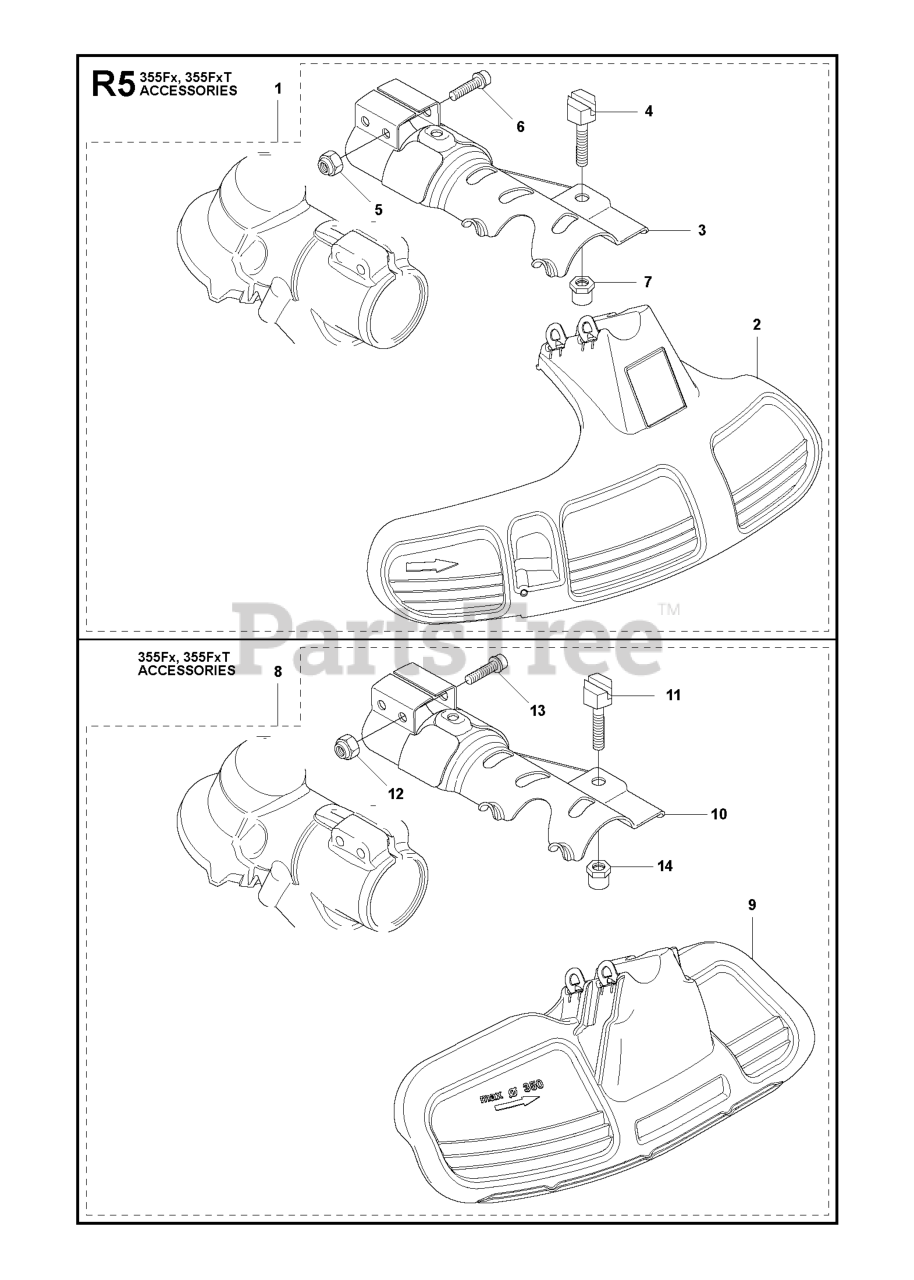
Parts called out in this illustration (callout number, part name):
1	GUARD ASSY
2	PROTECTION
3	ATTACHMENT PLATE
5	LOCKNUT M6
7	SPACING SLEEVE
8	GRASS BLADE GUARD ADAPTER INCL
9	BLADE GUARD GRASS
10	ATTACHMENT PLATE
12	LOCKNUT M6
14	SPACING SLEEVE
